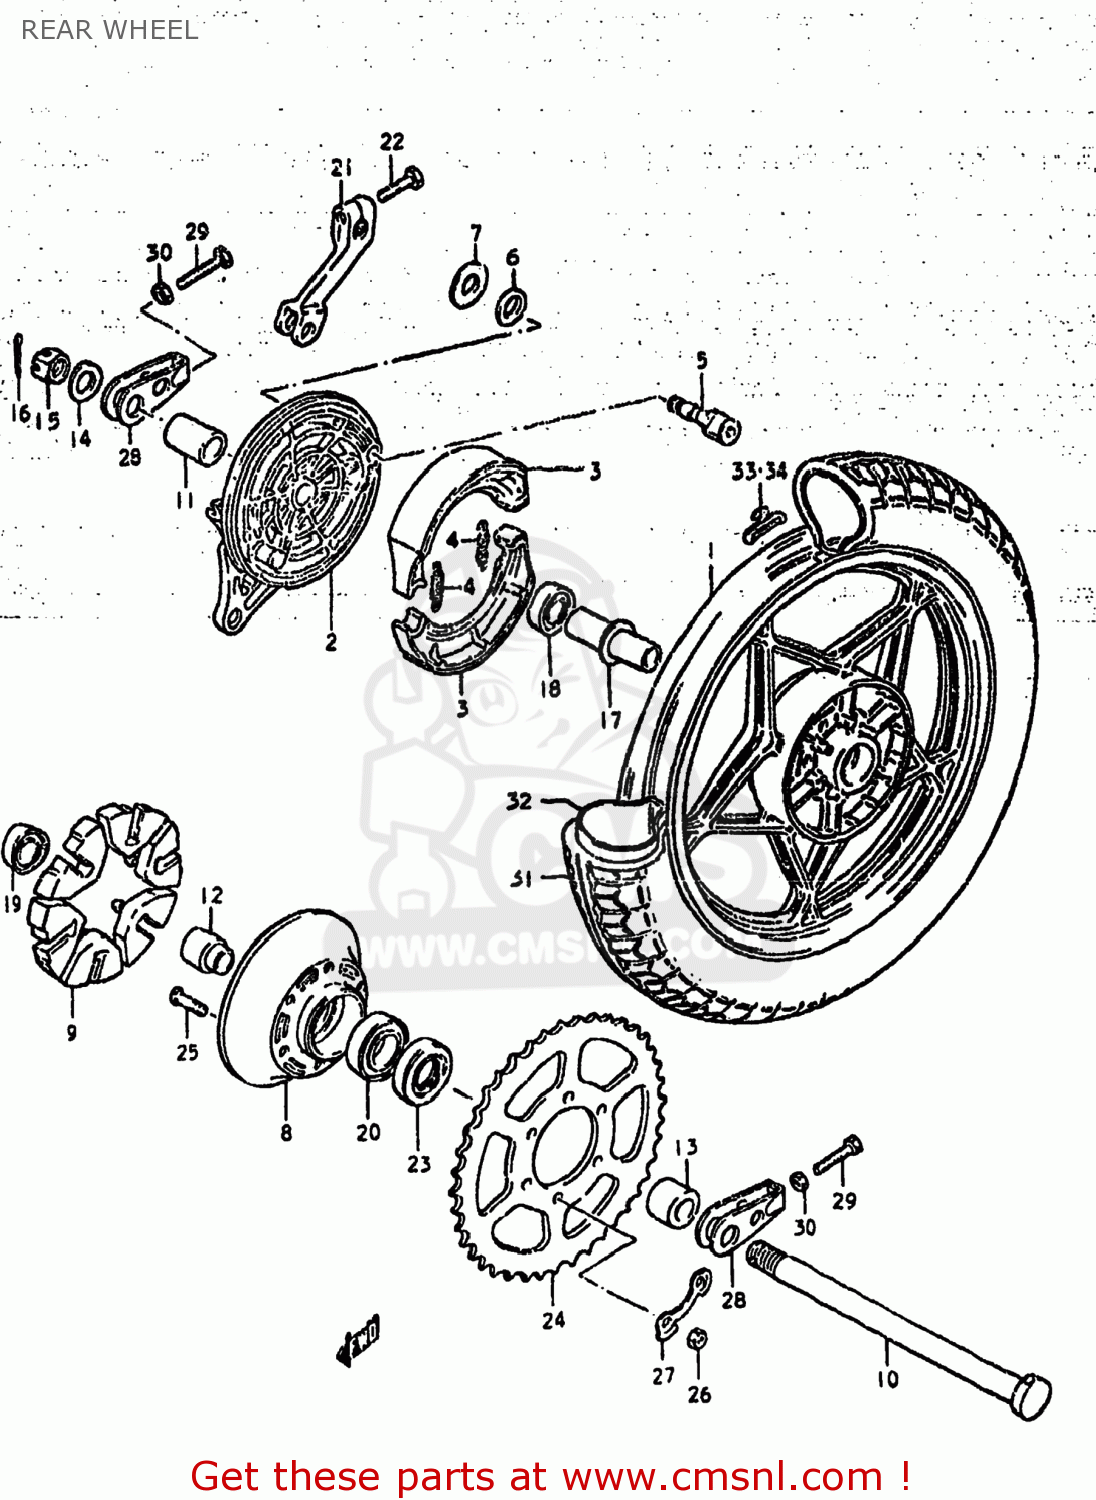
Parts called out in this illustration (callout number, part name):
1	WHEEL,REAR
2	PANEL,REAR HUB
3	SHOE SET,BRAKE
4	SPRING,BRAKE SHOE
5	CAM,FRONT BRAKE
6	O-RING,BOSS
7	WASHER (15X24X1.6)
8	DRUM,REAR SPROCKET MOUNT
9	ABSORBER,RR HUB SHOCK
10	AXLE,REAR
11	SPACER(17.5X28X44.8)
12	SPACER,REAR HUB BEARING
13	SPACER(17X30.5X22.3)
14	WASHER (17X30X3.2)
15	NUT
16	PIN,COTTER
17	SPACER
18	BEARING
19	BEARING
20	BEARING
21	LEVER,REAR BRAKE CAM
22	BOLT
23	OIL SEAL
24	SPROCKET,RR
25	BOLT
26	NUT
27	WASHER
28	ADJUSTER,CHAIN
29	BOLT 8X50
30	NUT
31	TIRE
32	TUBE ASSEMBLY,WHEEL,INNER
33	BALANCER,WHEEL
34	BALANCER,WHEEL
